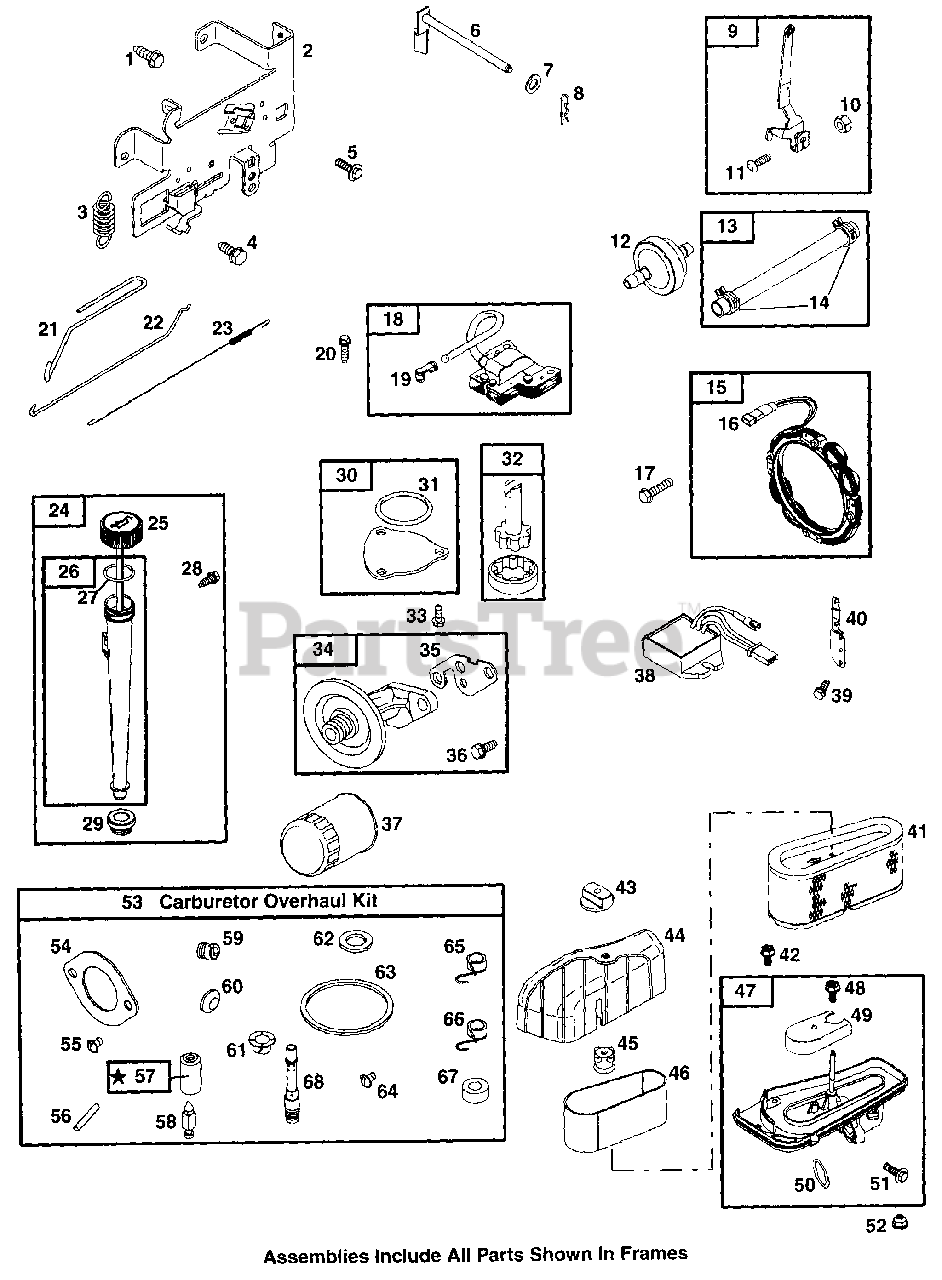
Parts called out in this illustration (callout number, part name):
1	Screw (Control Bracket)
2	Control Bracket
3	Governor Spring
4	Screw (Remote Choke Stop)
5	Screw (Remote Choke Stop)
6	Governor Crank
7	Washer (Governor Crank)
8	Cotter Pin
9	Governor Control Lever
10	Nut (Governor Control Lever)
11	Bolt (Governor Control Lever)
12	Fuel Filter
13	Fuel Line
14	Hose Clamp
15	Alternator
16	Alternator Wire
17	Screw (Alternator)
18	Magneto Armature
19	Sparkplug Terminal
20	Screw (Magneto Armature)
21	Choke Link
22	Mechanical Governor Link
23	Governor Link Spring
24	Dipstick/Tube Assembly
26	Dipstick Tube
27	Dipstick/Tube Seal
28	Screw (Dipstick Tube)
29	Dipstick Tube Seal
30	Oil Pump Cover
31	O-Ring Seal (Oil Pump Cover)
32	Oil Pump
33	Screw (Oil Pump Cover)
34	Oil Filter Adapter
35	Oil Adapter Gasket
36	Screw (Oil Filter Adapter)
37	Oil Filter
38	Regulator
39	Screw (Mounting Bracket)
40	Mounting Bracket
41	Air Cleaner Cartridge Filter
42	Screw (Air Cleaner Base)
43	Air Cleaner Knob
44	Air Cleaner Cover
45	Air Cleaner Stud Seal
46	Pre-Cleaner Filter
47	Air Cleaner Base
48	Screw (Carburetor Shield)
49	Carburetor Shield
50	O-Ring Seal (Air Cleaner Base)
51	Screw (Cable Clamp)
52	Nut (Air Cleaner Base)
53	Carburetor Overhaul Kit
54	Intake Gasket
55	Screw (Throttle Valve)
56	Float Hinge Pin
57	Inlet Seat (Gravity Feed)
58	Float Needle Valve
59	Main Jet (Standard)
60	Welch Plug
61	Throttle Shaft Bushing
62	Sealing Washer
63	Float Bowl Gasket
64	Screw (Choke Valve)
65	Spring/Seal Assy
66	Spring/Seal Assy
67	Throttle Shaft Seal
68	Carburetor Nozzle
